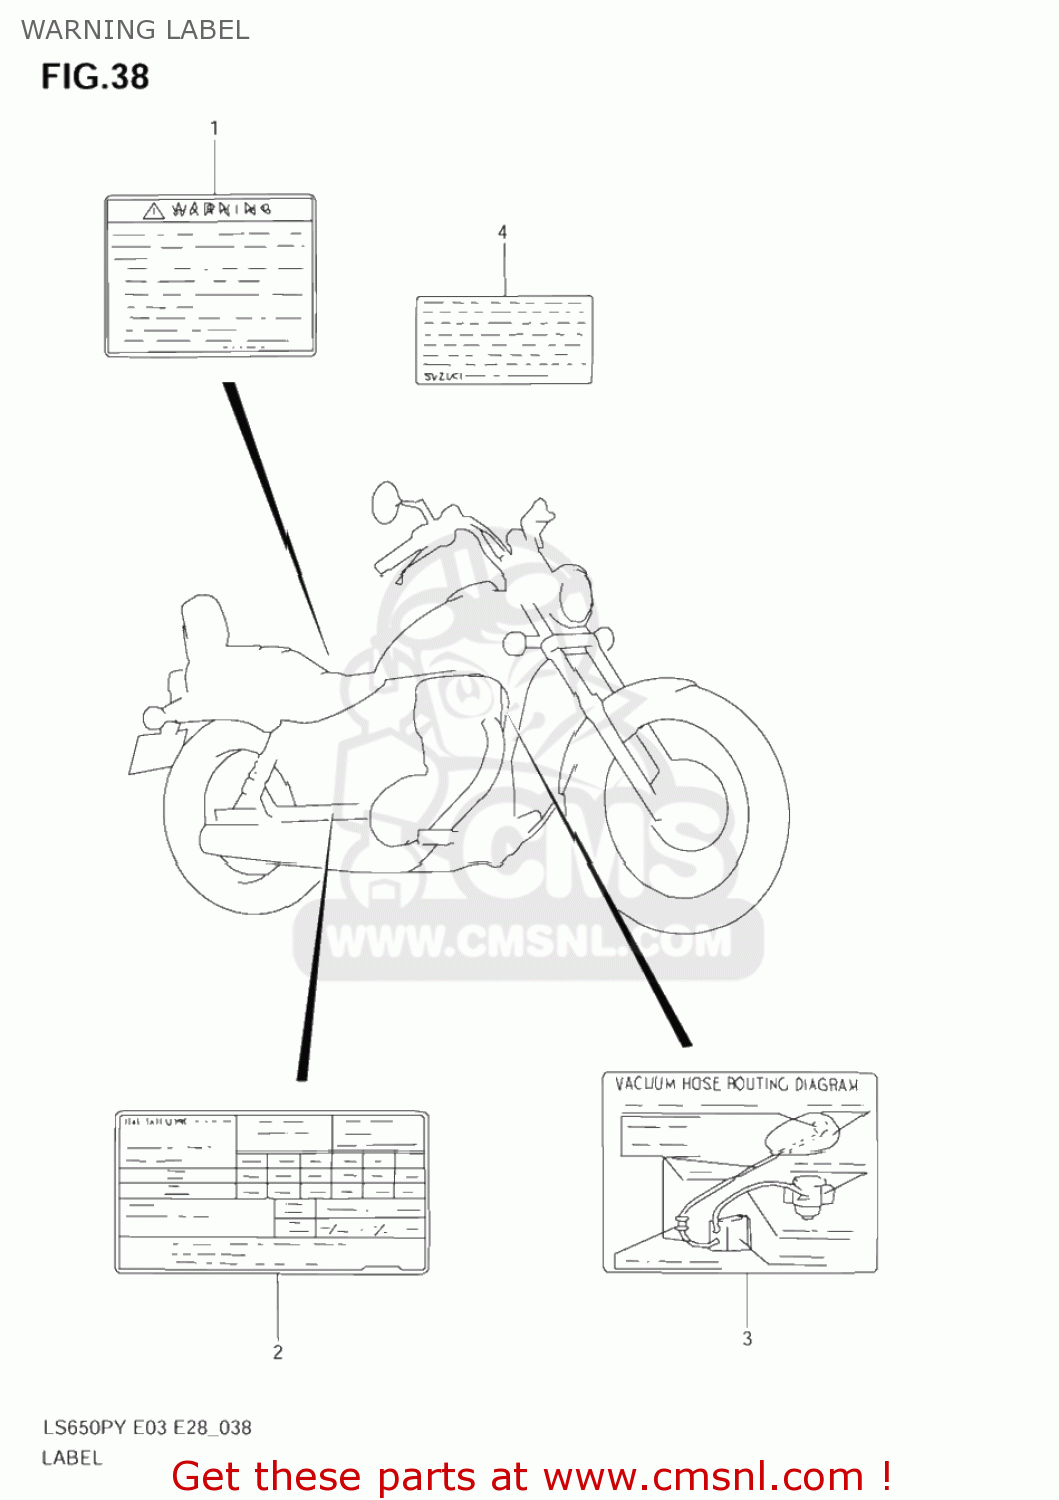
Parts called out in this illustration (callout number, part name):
1	LABEL,GENERAL WARNING
2	LABEL, TIRE INFORMATION
3	LABEL (VACUUM HOSE ROUTING)
4	LABEL,MANUAL NOTICE
5	MANUAL,OWNER'S
